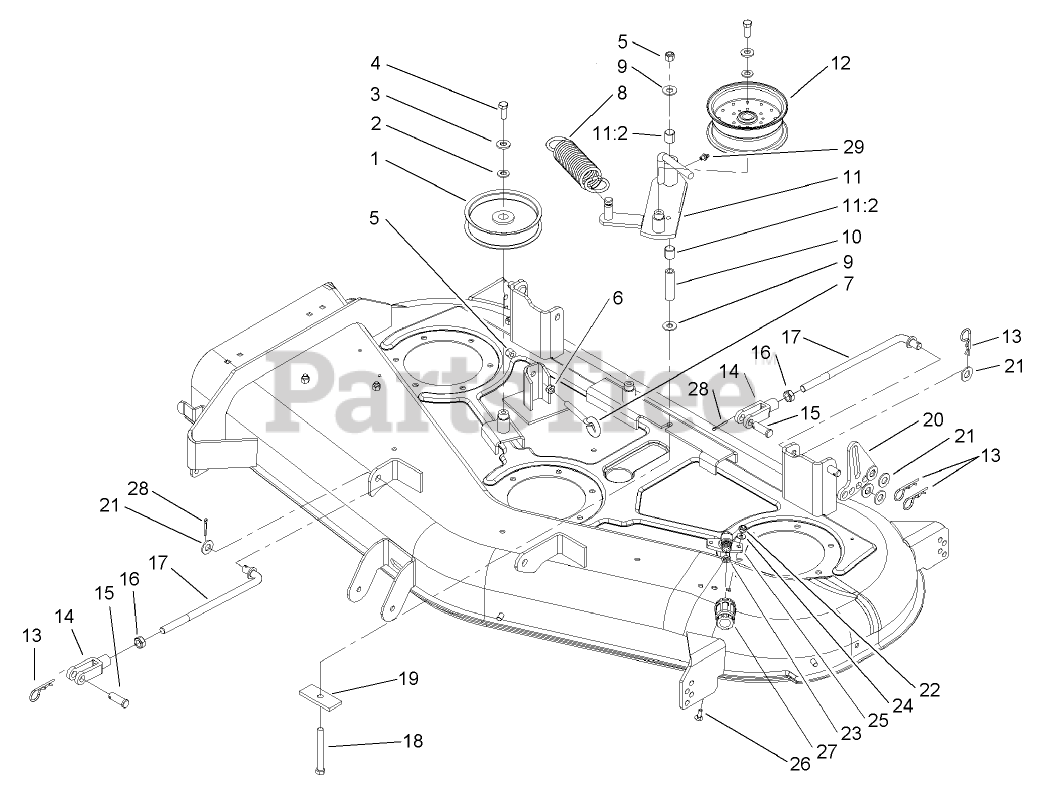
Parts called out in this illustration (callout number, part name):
1	PULLEY-IDLER
2	WASHER-FLAT
3	WASHER-BELLEVILLE
4	SCREW-HH
5	NUT-LOCK, NI
6	NUT-HEX
7	BOLT-EYE
9	WASHER-HARDENED
10	BUSHING-PIVOT, IDLER
11	IDLER ARM ASM
11:2	SLEEVE-BEARING
13	PIN-COTTER
14	CLEVIS
15	PIN-CLEVIS
16	NUT-JAM
18	SCREW-HH
19	PLATE-BOLT RETAINER
20	LINK-HOC, ADJUSTING
21	WASHER-FLAT
22	NUT-LOCK, NI
23	O-RING
24	WASHER-FLAT
26	BOLT-CARR
27	CONNECTOR-HOSE
28	PIN-COTTER
29	FITTING-GREASE
